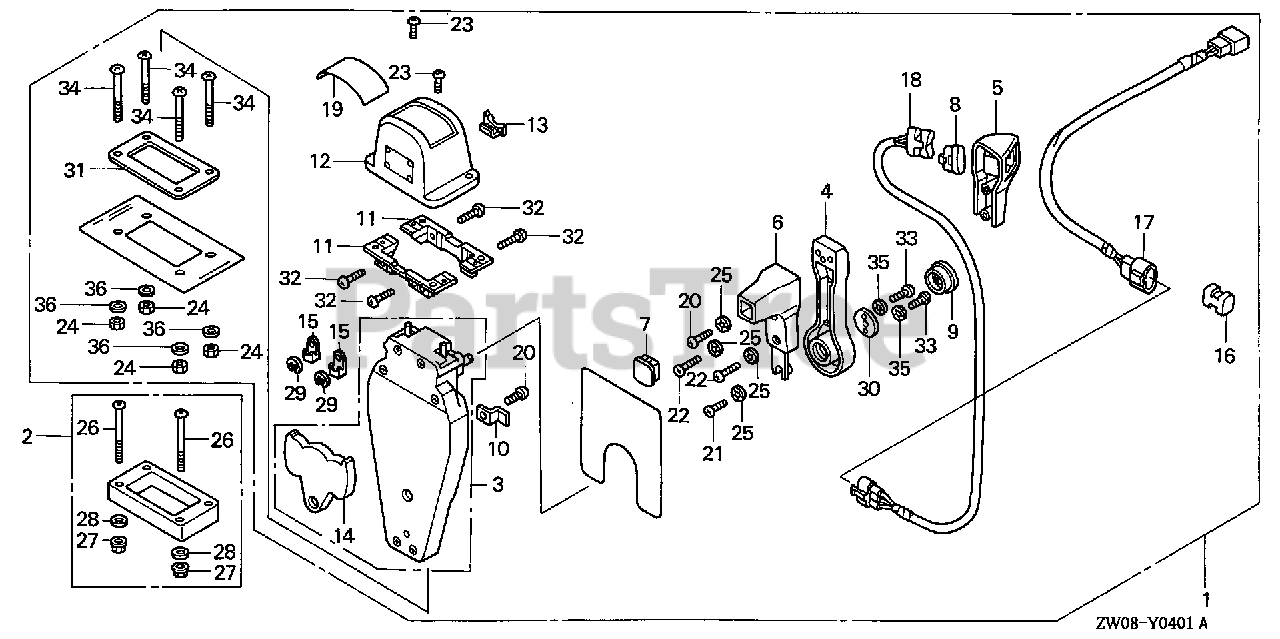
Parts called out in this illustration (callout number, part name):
1	BOX KIT, L. REMOTE CONTROL (TOP MOUNT SINGLE)
2	SPACER KIT, REMOTE CONTROL BOX (TOP MOUNT SINGLE)
3	HOUSING ASSY., R. (INNER) (TOP MOUNT)
4	HANDLE, REMOTE CONTROL
5	COVER, R. GRIP
6	GRIP, REMOTE CONTROL HANDLE
7	CAP, GRIP
8	CAP, SWITCH
9	BUTTON, THROTTLE
10	PLATE, CABLE CLAMP
11	BRACKET, REMOTE CONTROL HOUSING
12	HOUSING, REMOTE CONTROL BOX
13	HOUSING, LEAD
14	PLATE, DWELL
15	TERMINAL, CABLE
16	SPACER, CABLE CLAMP
17	SUB-HARNESS ASSY., POWER TRIM-TILT (B)
18	SWITCH ASSY., POWER TRIM-TILT
19	MARK, REMOTE CONTROL (SINGLE)
20	SCREW, PAN (5X16)
21	SCREW, PAN (5X10)
22	SCREW, PAN (5X20)
23	SCREW, PAN (4X10)
24	NUT, HEX. (5MM)
25	WASHER, LOCK (5MM)
26	SCREW, PAN (5X65)
27	NUT, FLANGE (5MM)
28	WASHER, PLAIN (5MM)
29	E-RING (6MM)
30	PLATE, HANDLE
31	GASKET, SINGLE
32	SCREW, PAN (5X18)
33	SCREW, PAN (6X18)
34	SCREW, PAN (5X40)
35	WASHER, LOCK (6MM)
36	WASHER, PLAIN (5MM)
